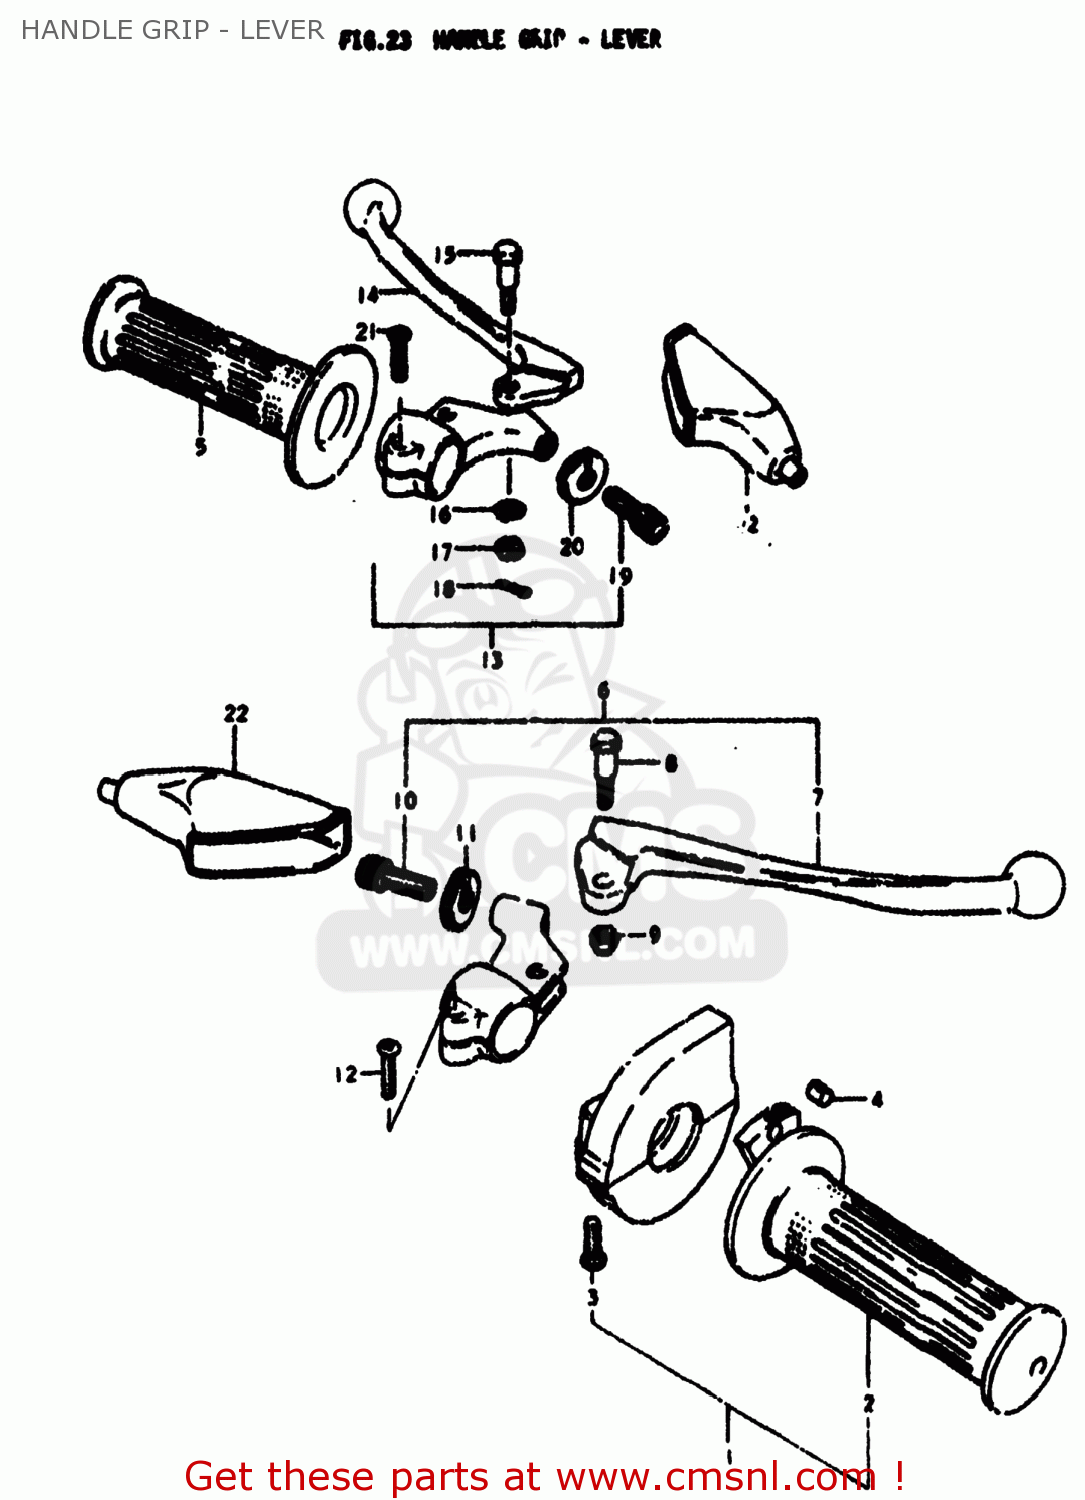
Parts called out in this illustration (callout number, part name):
1	GRIP ASSY,THROTTLE
2	GRIP,THROTTLE
3	SCREW
4	PIECE,THROTTLE END
5	GRIP,LEFT
6	LEVER ASSY,BRAKE
7	LEVER,BRAKE
8	BOLT,LEVER
9	NUT 6MM
10	ADJUSTER,CABLE
11	NUT,CABLE ADJUSTER
12	SCREW
13	LEVER ASSEMBLY
14	LEVER,CLUTCH
15	BOLT,LEVER
16	LOCK WASHER
17	NUT,LEVER FITTNG
18	COTTER PIN
19	ADJUSTER,CABLE
20	NUT,CABLE ADJUSTER
21	SCREW
22	COVER,CLUTCH LEVER
